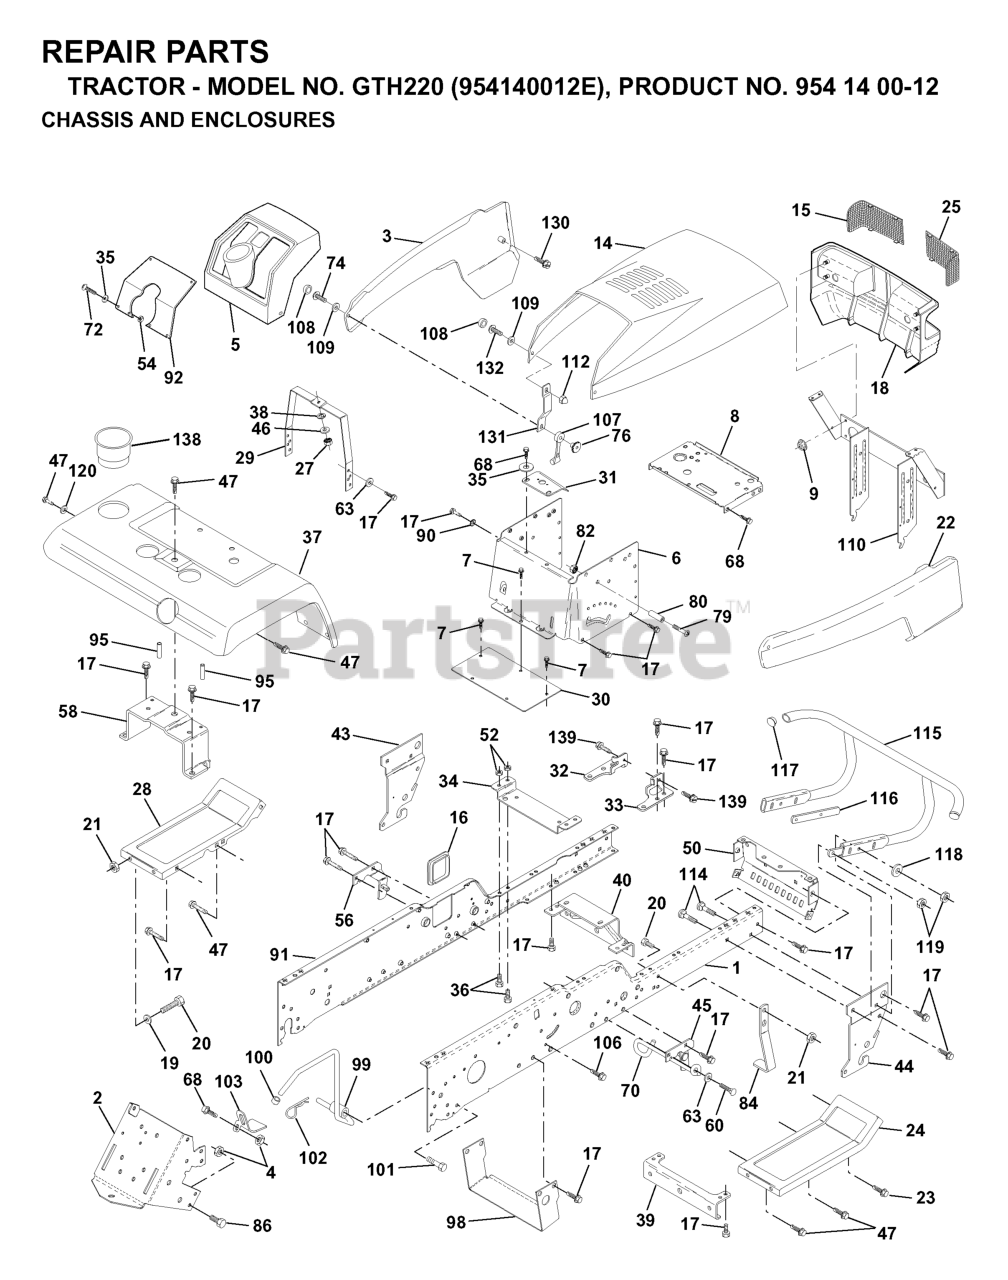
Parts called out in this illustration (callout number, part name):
1	RAIL, FRAME RH
2	DRAWBAR-GT
3	SIDE PANEL LH
4	Nut, Lock Hex 7/16 Unc
6	DASH VGT, LOWER
7	SCREW
8	SUPPORT, BATTERY
9	PAL NUT LT
14	HOOD ASM PNT
16	COVER ACCESS
17	SCREW
18	GRILLE.ASM.HUSQVARNA.YTGT
19	WASHER
20	BOLT
22	PANEL ASM SD RH
23	SCREW GTV
24	FOOTREST RH
25	LENS.RH.HUSQVARNA.YTGT.CL
27	NUT
28	FOOT REST LH
29	DASH SUPT YP
30	SADDLE.HYDRO.95
31	BRACKET SUPT 1-PC VGT STEERING
34	ENGINE SUPPORT BRKT
35	WASHER
36	BOLT.FIN.HEX.5/16-18X3/4
38	LOCKWASHER
39	FRONT AXLE BRACKET
40	BRACKET, SUPPORT AXLE/ENGINE
43	FRONT SUSPENSION BRKT LH
44	FRONT SUSPENSION BRKT RH
45	BRACKET SUSP RH
50	BRACKET, CHASSIS FRONT
52	NUT.71038.31-18.HEX.NYLOCK
54	NUT
56	BRACKET ASM, SUSP CHASSIS
58	FENDER BRKT
60	SCREW
63	WASHER
68	Screw 5/16-18 x 1/2 Hex, Self Tapping 5/16-18 x 1/2
70	BELT GUIDE
72	Screw, Machine, Truss Head 5/16-18 UNC x 3/4
74	SCREW
76	WELDNUT
79	RP SCREW
82	NUT **
84	MOWER STOP
86	BOLT
90	LOCKWASHER
91	RAIL, FRAME LH
92	DASH PLATE
95	NUT-PUSH YT
98	BRACKET CHASSIS
99	ROD ASMBLY BYPASS
100	CAP
101	SCREW LT
102	RETAINER M
103	BRACKET LOCK BYPASS
106	SCREW
107	LATCH.HOOD.
108	SNAP CAP LT
110	PIVOT ASM GRL/HD
112	NUT
114	BOLT.3/8-14X1.25
116	BRACKET BUMPER
117	PLUG PLASTIC
118	WASHER
120	WASHER
130	Screw, SLTD Hex Hd. W/Pl Washer
131	BRACKET.SUPPORT.HOOD/PANEL.NLA
132	SCREW 10-24X3/8
